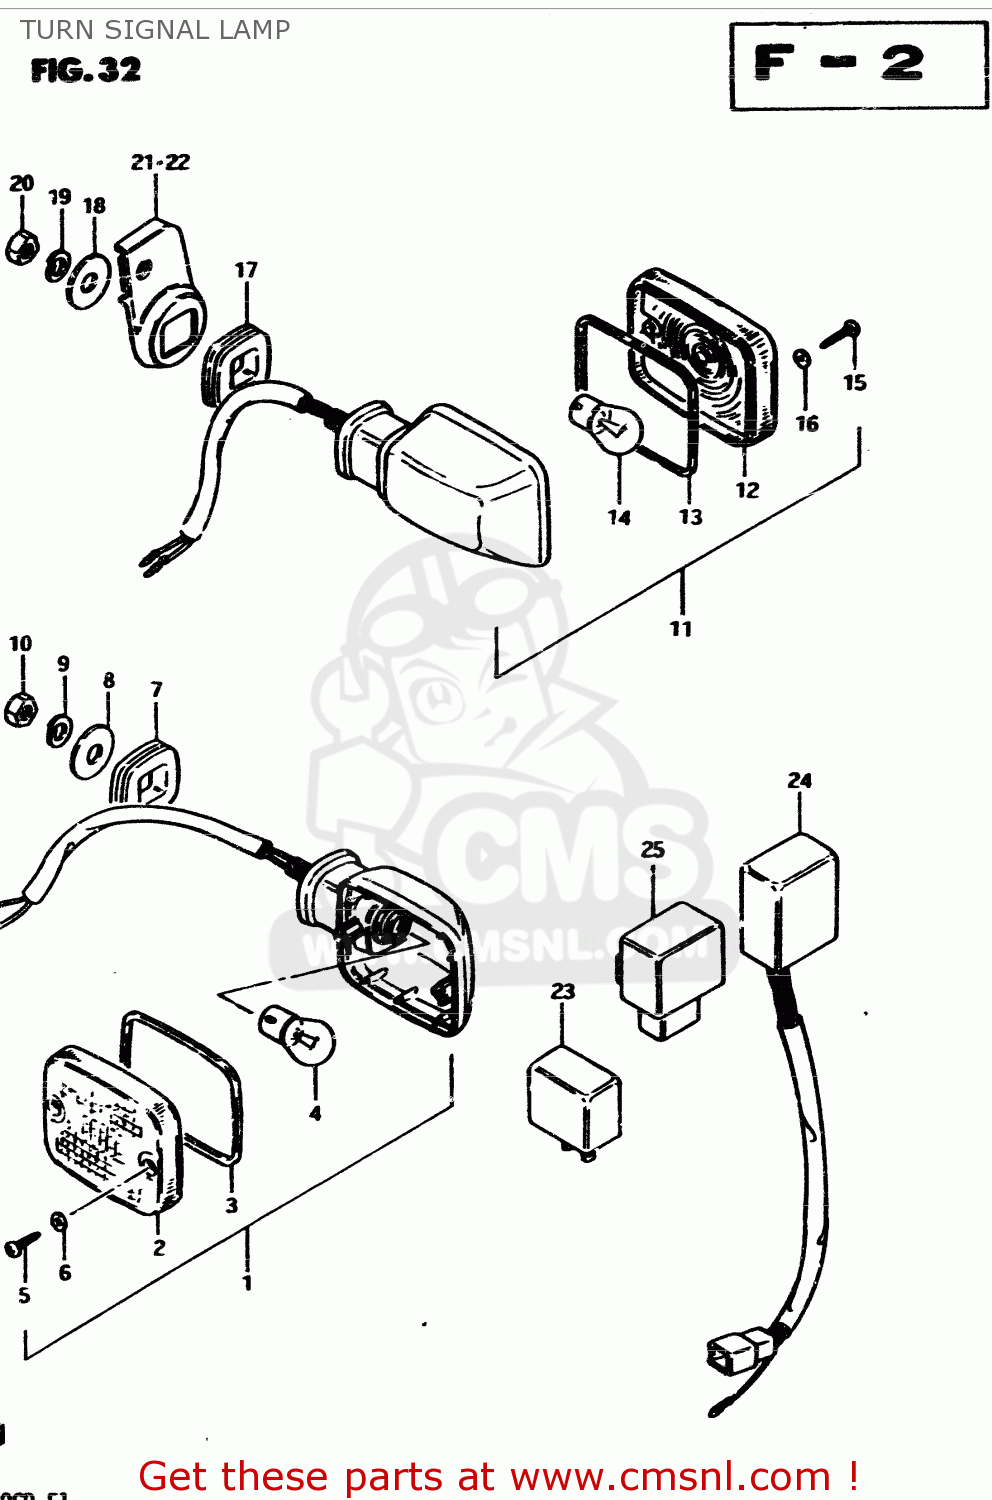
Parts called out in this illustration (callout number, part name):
1	LAMP ASSEMBLY,FRONT TURN SIGNAL
2	LENS
3	GASKET (NAS)
4	BULB(12V23W,STANLEY,A4577A)
5	SCREW
6	GASKET (NAS)
7	CUSHION
8	WASHER (10.5X30X2.3)
9	LOCK WASHER
10	NUT
11	LAMP ASSEMBLY,FRONT TURN SIGNAL
12	LENS
13	GASKET (NAS)
14	BULB(12V23W,STANLEY,A4577A)
15	SCREW
16	GASKET (NAS)
17	CUSHION
18	WASHER (10.5X30X2.3)
19	LOCK WASHER
20	NUT
21	BRACKET,REAR TURN SIGNAL
22	BRACKET,REAR TURN SIGNAL
23	RELAY ASSY,TURNSIGNAL
24	UNIT,TURN SIGNAL CONTROL
25	UNIT,TURN SIGNAL CONTROL
